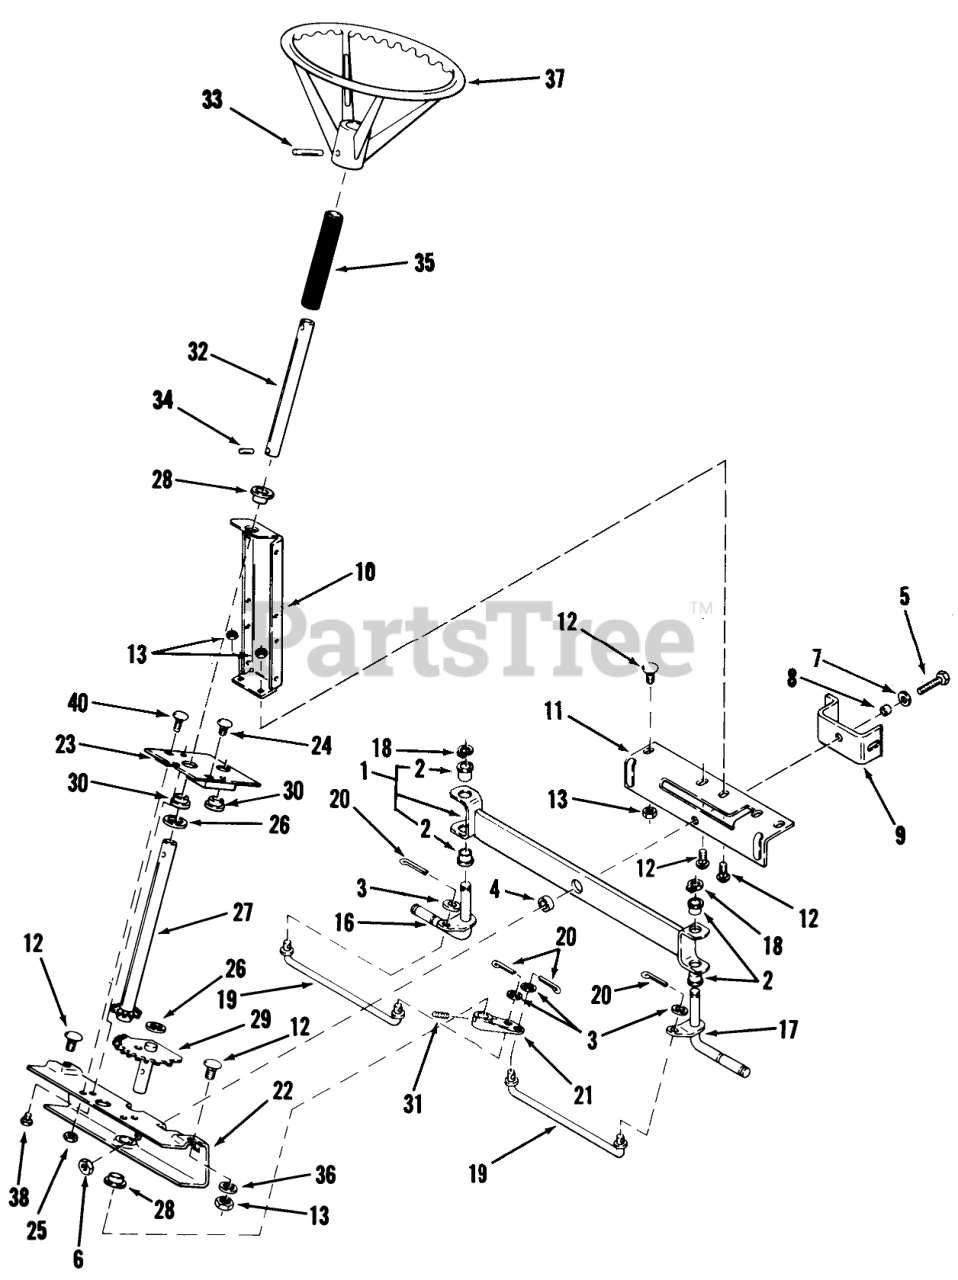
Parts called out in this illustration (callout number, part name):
1	ASSY-FRNT AXLE/BRG
2	BUSHING
17	ASSY-SPINDLE LH *R
21	ARM-STEERING
28	BEARING
29	ASSY-STEERING SEC *R (NS)
30	BUSHING
31	PIN-ROLL, SPIROL
34	SPIROL PIN
38	Bolt
